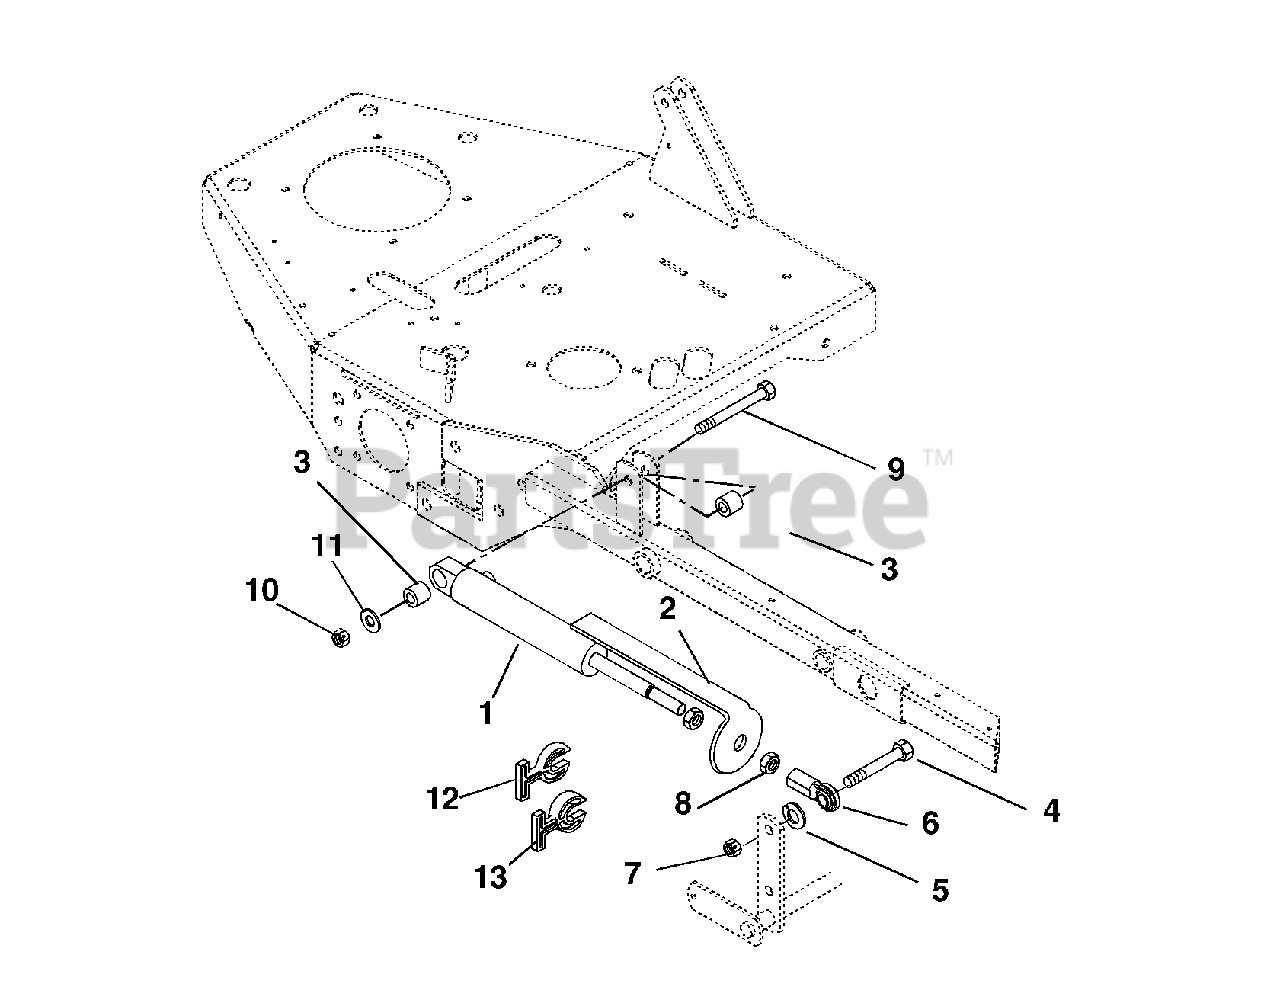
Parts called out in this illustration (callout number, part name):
1	Cylinder-Hydraulic Lift
2	Strap-Height of Cut Indicator
3	Bushing .516 x 1.000 x 1.05
4	Bolt-Hex .62-11 x 2.25 Grade 8
5	Washer-Lock .62 x .156
6	Rod End-Right Hand-Female .63
7	Nut-Locking-Center .62-11
8	Nut-Jam .63-18
9	Bolt-Hex .50-13 x 3.75 Grade 5
10	Nut-Locking-Center .50-13
11	Washer-Flat-Steel .515 x 1.625 x .25
12	Stop, Cylinder .34 Thick
13	Stop, Cylinder .68 Thick
